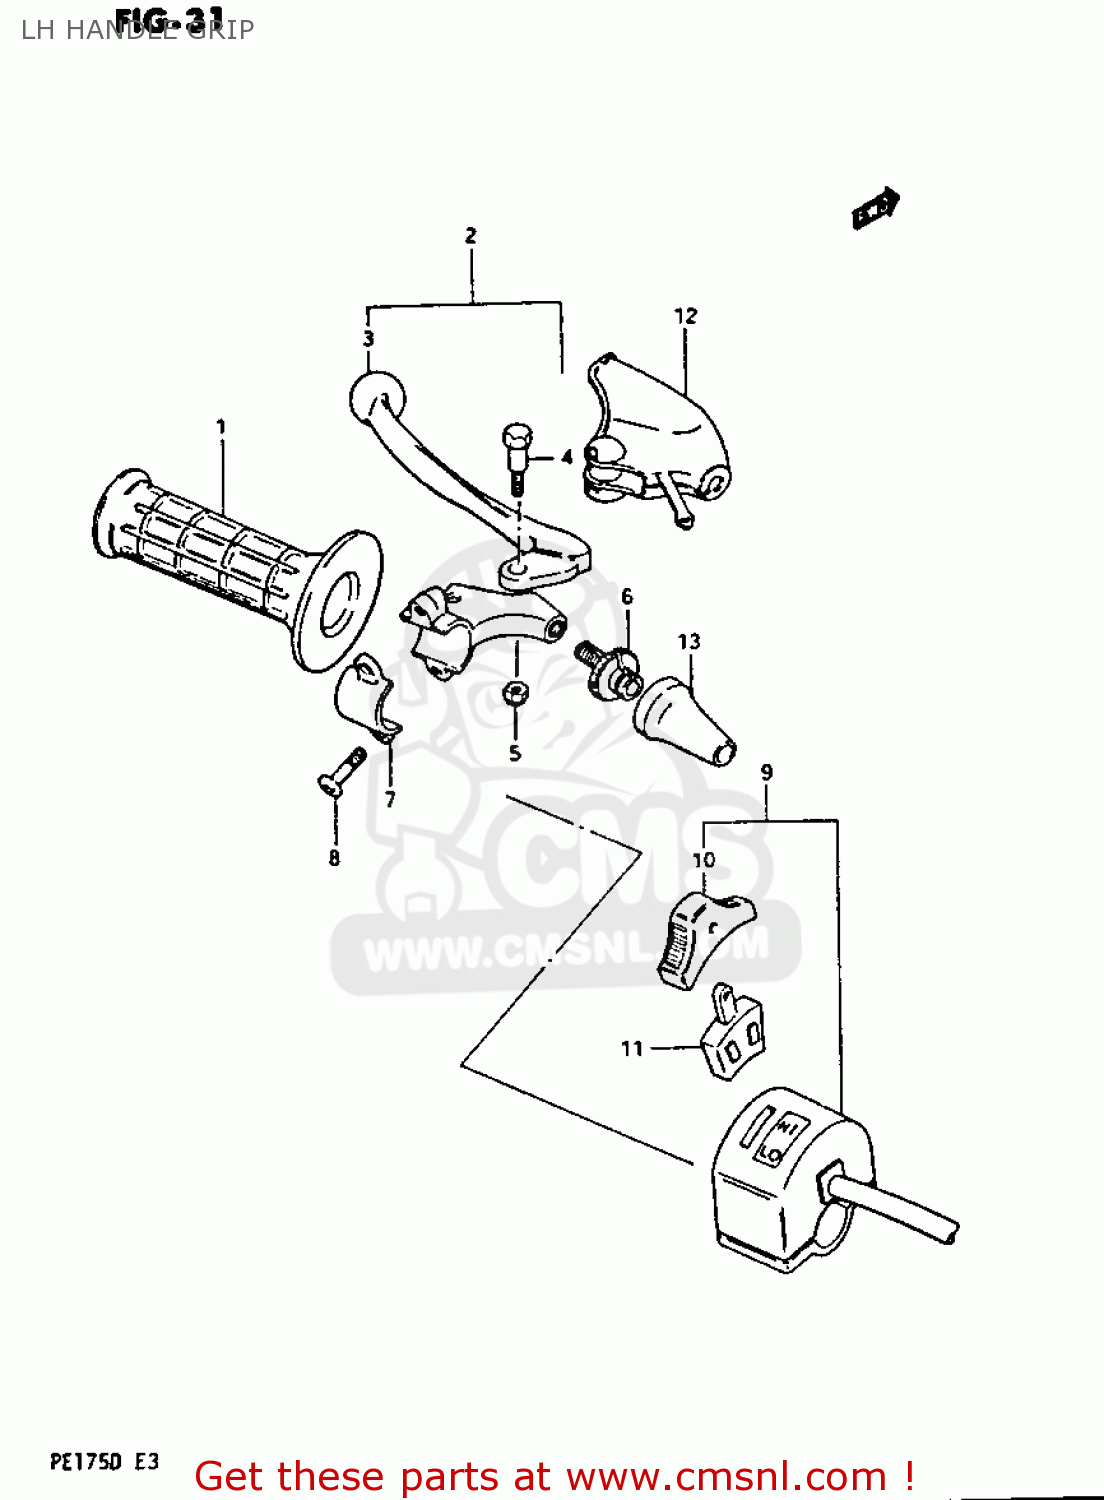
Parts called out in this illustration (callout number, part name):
1	GRIP,LEFT
2	LEVER ASSEMBLY,CLUTCH
3	LEVER,CLUTCH
4	BOLT,LEVER PIVOT
5	NUT 6MM
6	ADJUSTER,CABLE
7	BRACKET,LEVER
8	SCREW
9	SWITCH,DIMMER
10	KNOB,LIGHTING & DIMMER
11	BLOCK,LIGHTING/DIMMER
12	COVER,BRAKE LEVER
13	BOOT,CLUTCH CABLE
